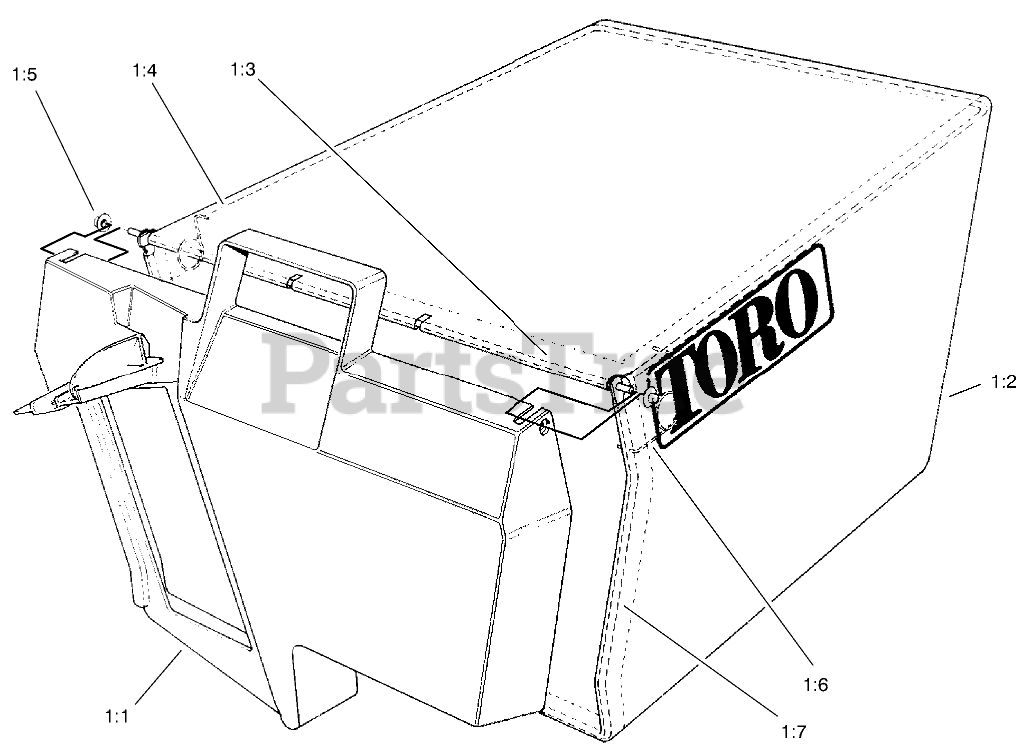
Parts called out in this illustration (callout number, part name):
1:1	DOOR-BAG
1:2	Bag-Grass
1:3	HINGE-DOOR, BAG
1:4	FRAME-BAG, UPPER
1:5	NUT-PUSH
1:6	SPRING
1:7	FRAME-BAG
